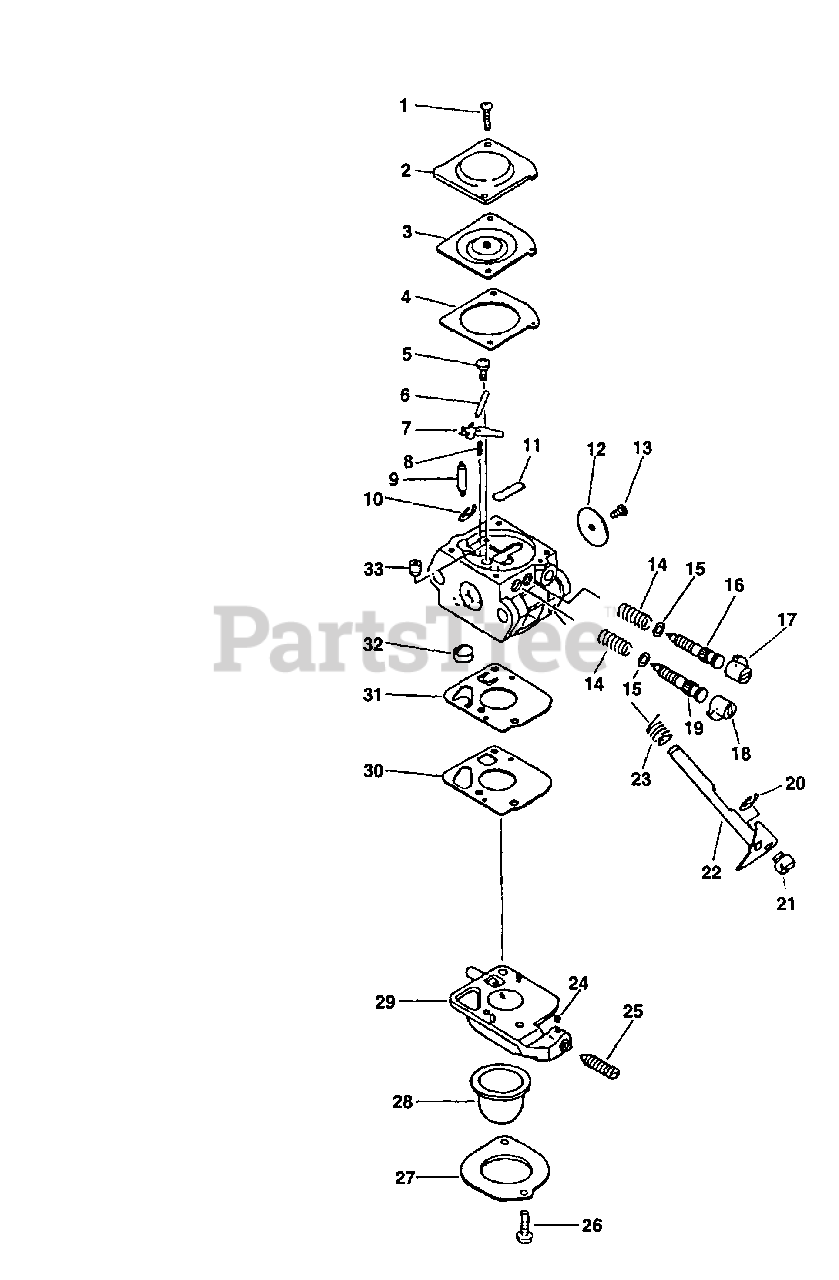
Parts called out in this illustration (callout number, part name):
2	COVER, METERING DIAPHRAGM
3	DIAPHRAGM, METERING
4	GASKET, METERING
6	PIN, METERING LEVER
7	LEVER, METERING
8	SPRING, METERING LEVER
9	VALVE, INLET NEEDLE
11	PLUG, WELCH
12	VALVE, THROTTLE
14	SPRING, NEEDLE
16	NEEDLE, IDLE
17	CAP, LIMITER - WHITE
18	CAP, LIMITER - RED
19	NEEDLE, HIGH SPEED
22	SHAFT, THROTTLE
23	SPRING, THROTTLE RETURN
24	PIECE, FRICTION
25	SCREW, IDLE ADJUST
27	RETAINER
28	BULB, PURGE
29	BODY ASSY, PURGE
30	GASKET, PUMP
31	DIAPHRAGM, PUMP
32	STRAINER
33	NOZZLE, CHECK VALVE
